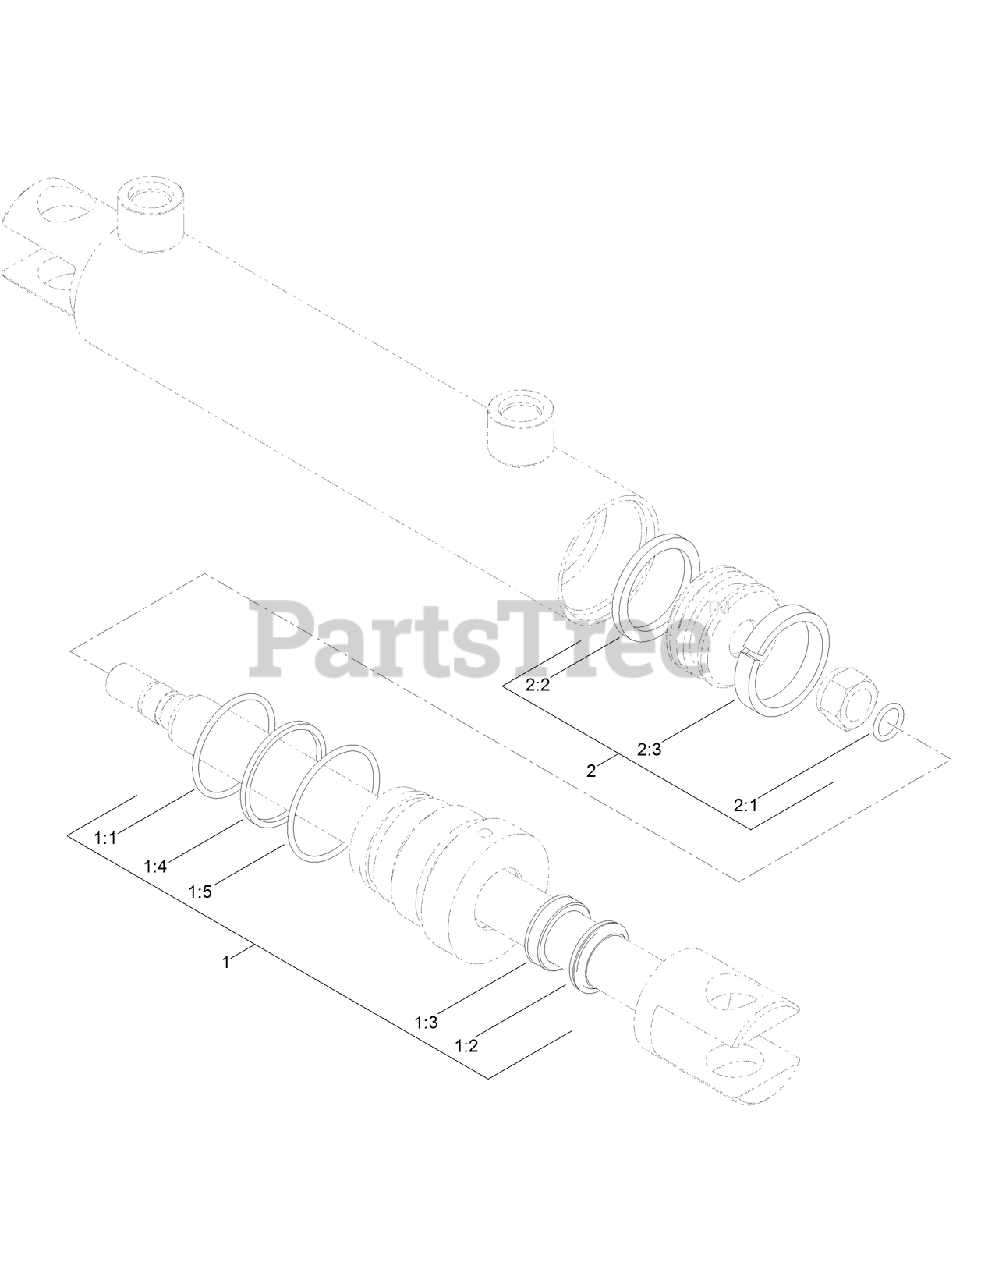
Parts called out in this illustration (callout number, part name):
1	GLAND SEAL KIT
1:1	O-RING
1:2	SEAL-WIPER, ROD
1:3	SEAL-ROD
1:4	Ring-Back Up
1:5	O-RING
2	PISTON SEAL KIT
2:1	O-RING
2:2	Seal-Psp
2:3	RING-WEAR
